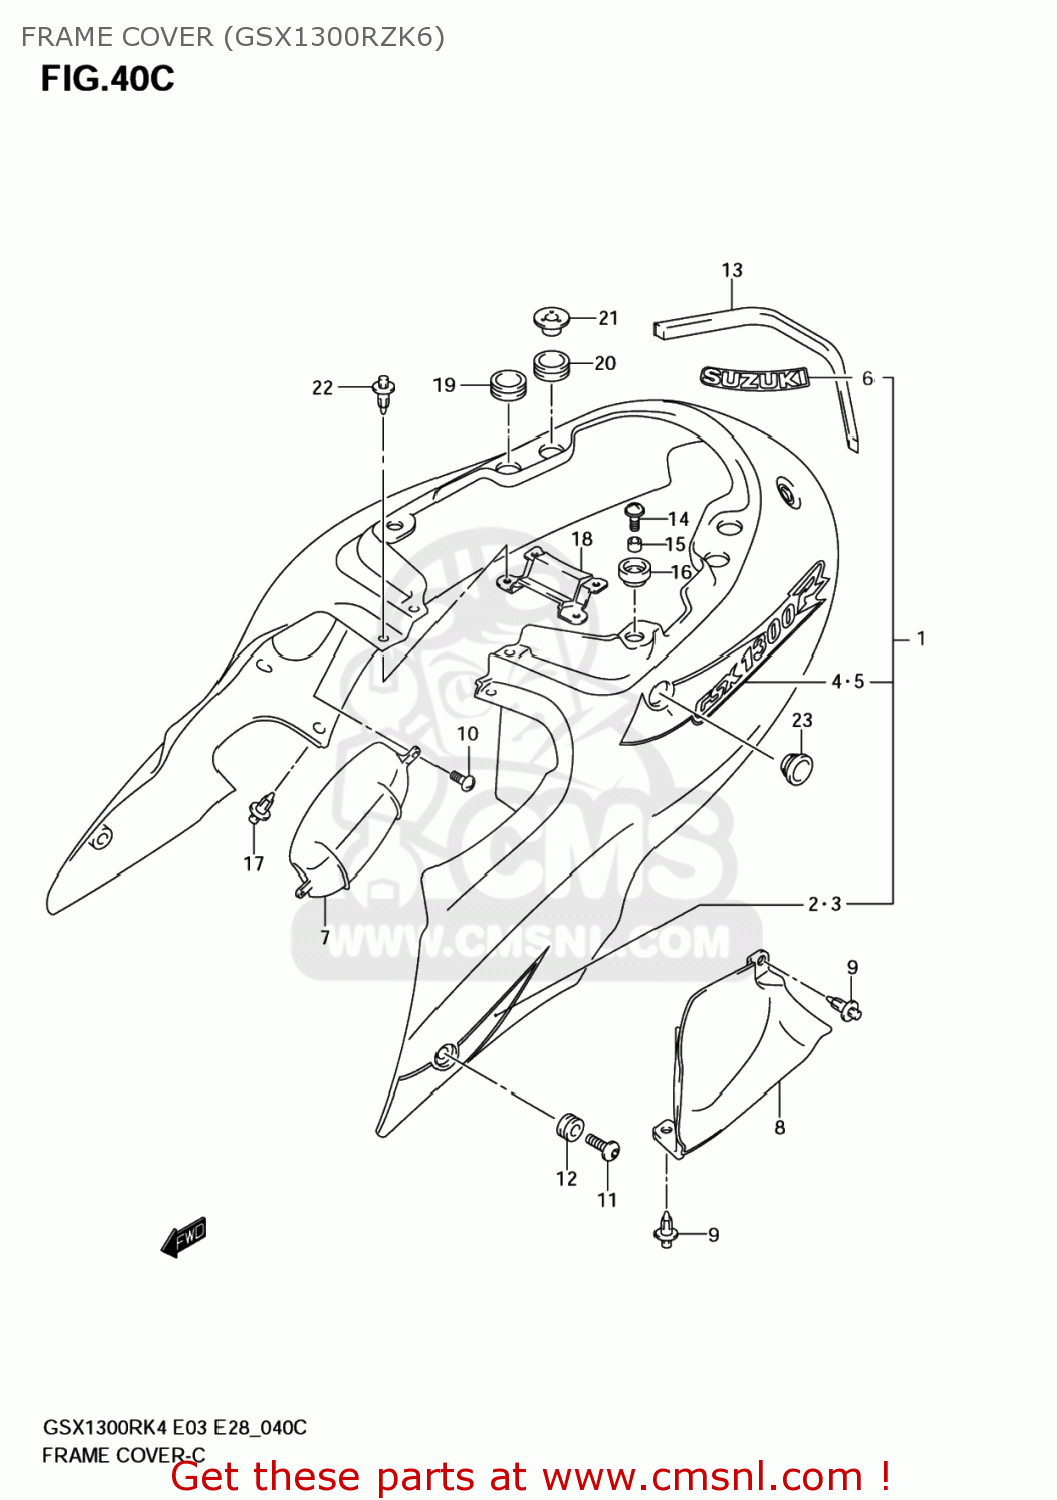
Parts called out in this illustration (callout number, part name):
1	COVER,FRAME(WHITE)
2	TAPE,FRAME COVER NO.1,R
3	TAPE,FRAME COVER NO.1,L
4	TAPE,FRAME COVER,R
5	TAPE,FRAME COVER,L
6	EMBLEM
7	CAP,FRAME COVER HOLE,R
8	CAP,FRAME COVER HOLE,L
9	CLIP(BLACK)
10	SCREW
11	SCREW(6X20)
12	CUSHION
13	CUSHION,FRAME COVER UPR
14	SCREW(6X20)
15	SPACER(6.5X10X11)
16	CUSHION
17	CLIP(BLACK)
18	COVER,FRAME CTR
19	CUSHION,FRAME COVER UPR RR
20	CUSHION,FRAME COVER UPR RR RR
21	WASHER,FRAME C
22	CLIP(BLACK)
23	CUSHION,FRAME COVER CTR
